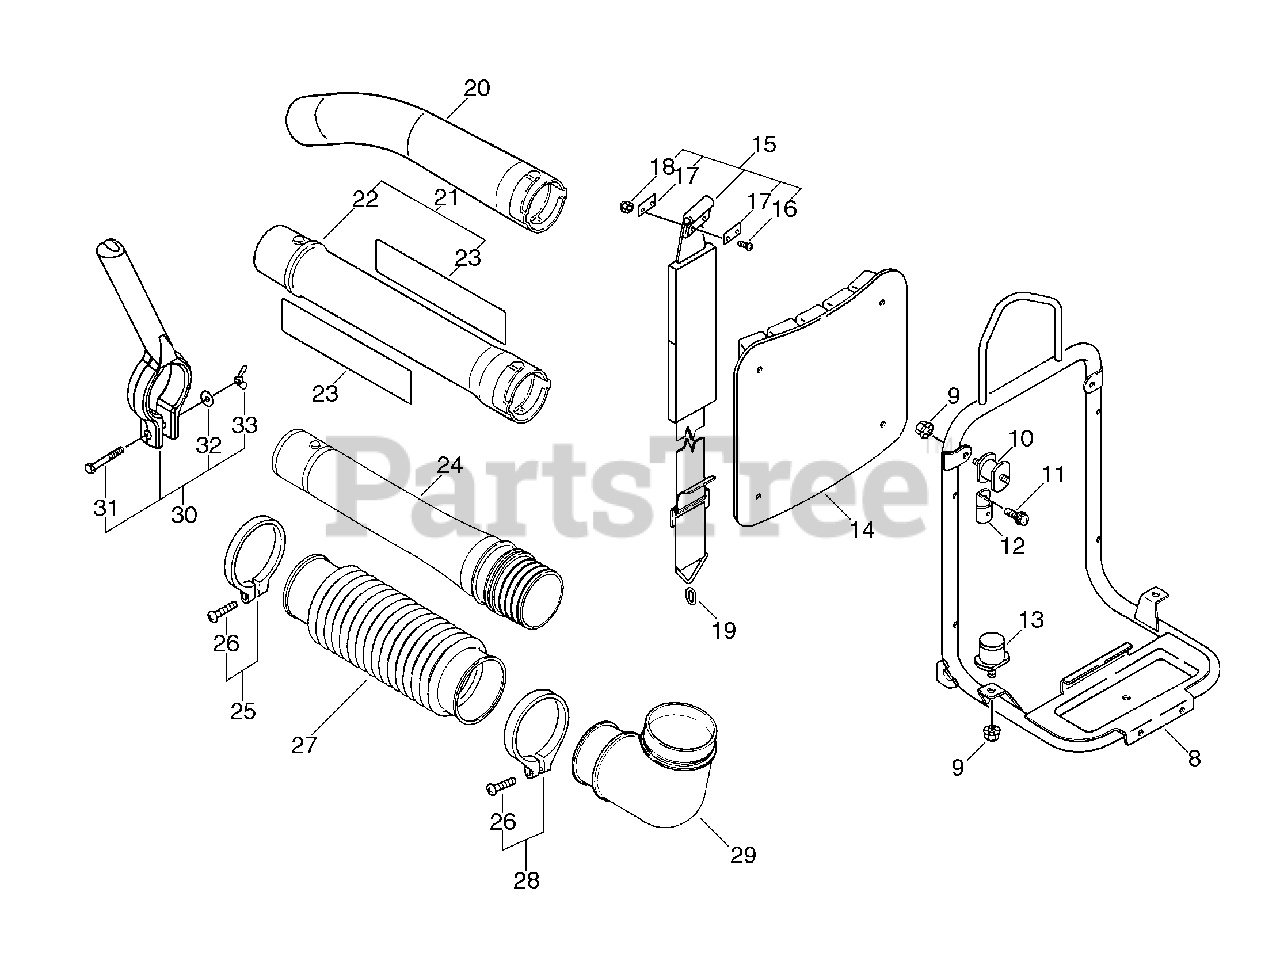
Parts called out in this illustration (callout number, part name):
8	FRAME, BACKPACK
9	NUT - 6 -- FLANGE
11	SCREW - 5X10
12	BRACKET, CUSHION
14	CUSHION, BACKPACK
15	BACKPACK STRAP ASSY
16	SCREW - 5X16
18	LOCKNUT - 5
19	RING, STRAP
20	TUBE, BLOWER - CURVED
21	BLOWER TUBE KIT - STRAIGHT
22	TUBE, BLOWER - STRAIGHT
23	LABEL - ECHO
24	TUBE, BLOWER - SWIVEL
25	CLAMP KIT
26	SCREW - 5X30
27	TUBE, BLOWER - FLEXIBLE
28	CLAMP KIT
29	TUBE, BLOWER - ELBOW
30	HANDLE ASSY
31	BOLT - 6X45
32	WASHER - 6
33	WINGNUT - 6
